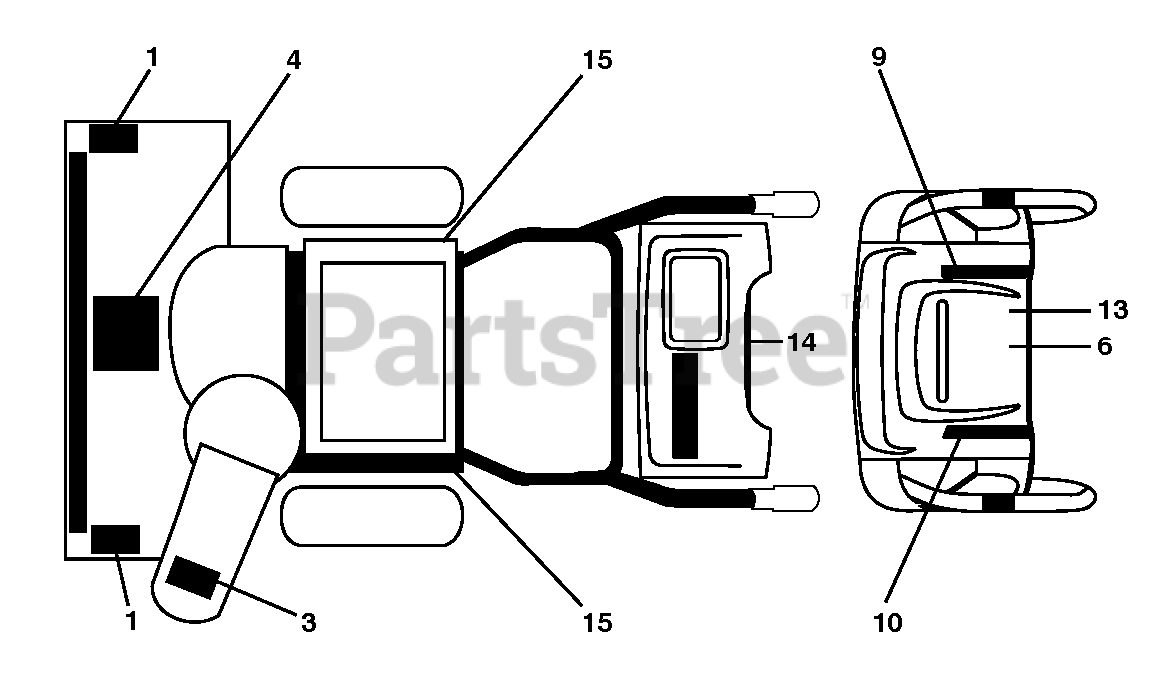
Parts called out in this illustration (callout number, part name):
1	DECAL.AUGER.SAFETY.
3	DECAL.CHUTE.SAFETY.EU/SC.17
4	DECAL.AUGER."
9	DECAL CONSOLE DECAL DECAL.SNOW
10	DECAL CONSOLE DECAL DECAL.SNOW
13	DECAL.CONSOLE.HAND.WARMER
14	DECAL.NOISE.LEV.105/CE.EAC.UKR
15	DECAL.BELT.GUARD.
